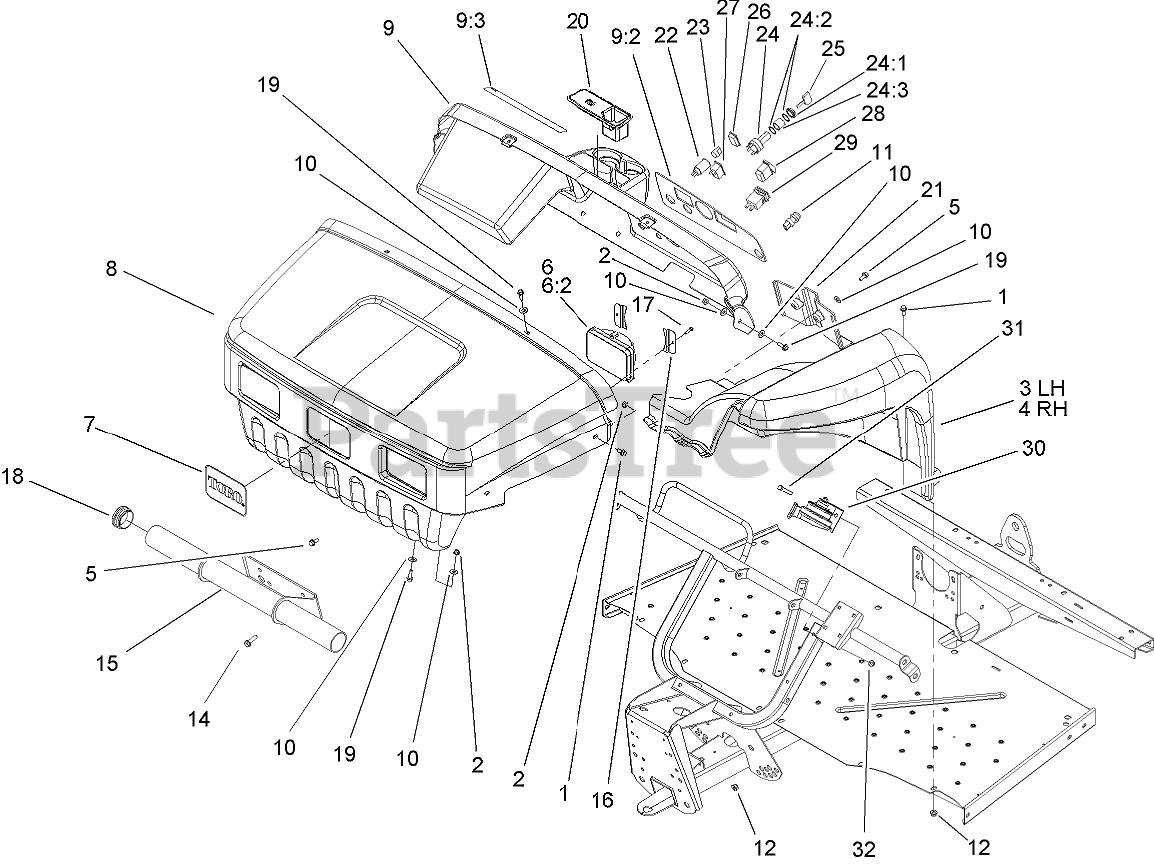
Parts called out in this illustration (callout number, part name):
1	SCREW-HHF
2	NUT-HF, NI
3	LH FENDER ASM
4	RH FENDER ASM
5	SCREW-HHF
6	HEADLIGHT
6:2	LENS-HEADLIGHT
7	DECAL
8	HOOD ASM
9	DASH ASM
9:2	DECAL-WARNING
9:3	DECAL-DANGER
10	WASHER-FLAT
11	BUTTON-HORN
12	NUT-HF, NI
15	BUMPER-TUBE
16	BRACKET-HEADLIGHT
17	SCREW-HWH
18	CAP-END
19	SCREW-HHF
20	PLUG-RUBBER
21	COVER-CHANNEL
22	POINT-POWER
24	Switch-Ignition
24:1	NUT-SWITCH, PLASTIC
24:2	WASHER-LOCK, INTERNAL
24:3	SPACER-SWITCH
25	KEY-IGNITION
26	PLUG-HOLE
27	INDICATOR-LIGHT, LOW-OIL PRESSURE
28	SWITCH
29	HOURMETER
31	SCREW-HH
32	NUT-HF, NI
